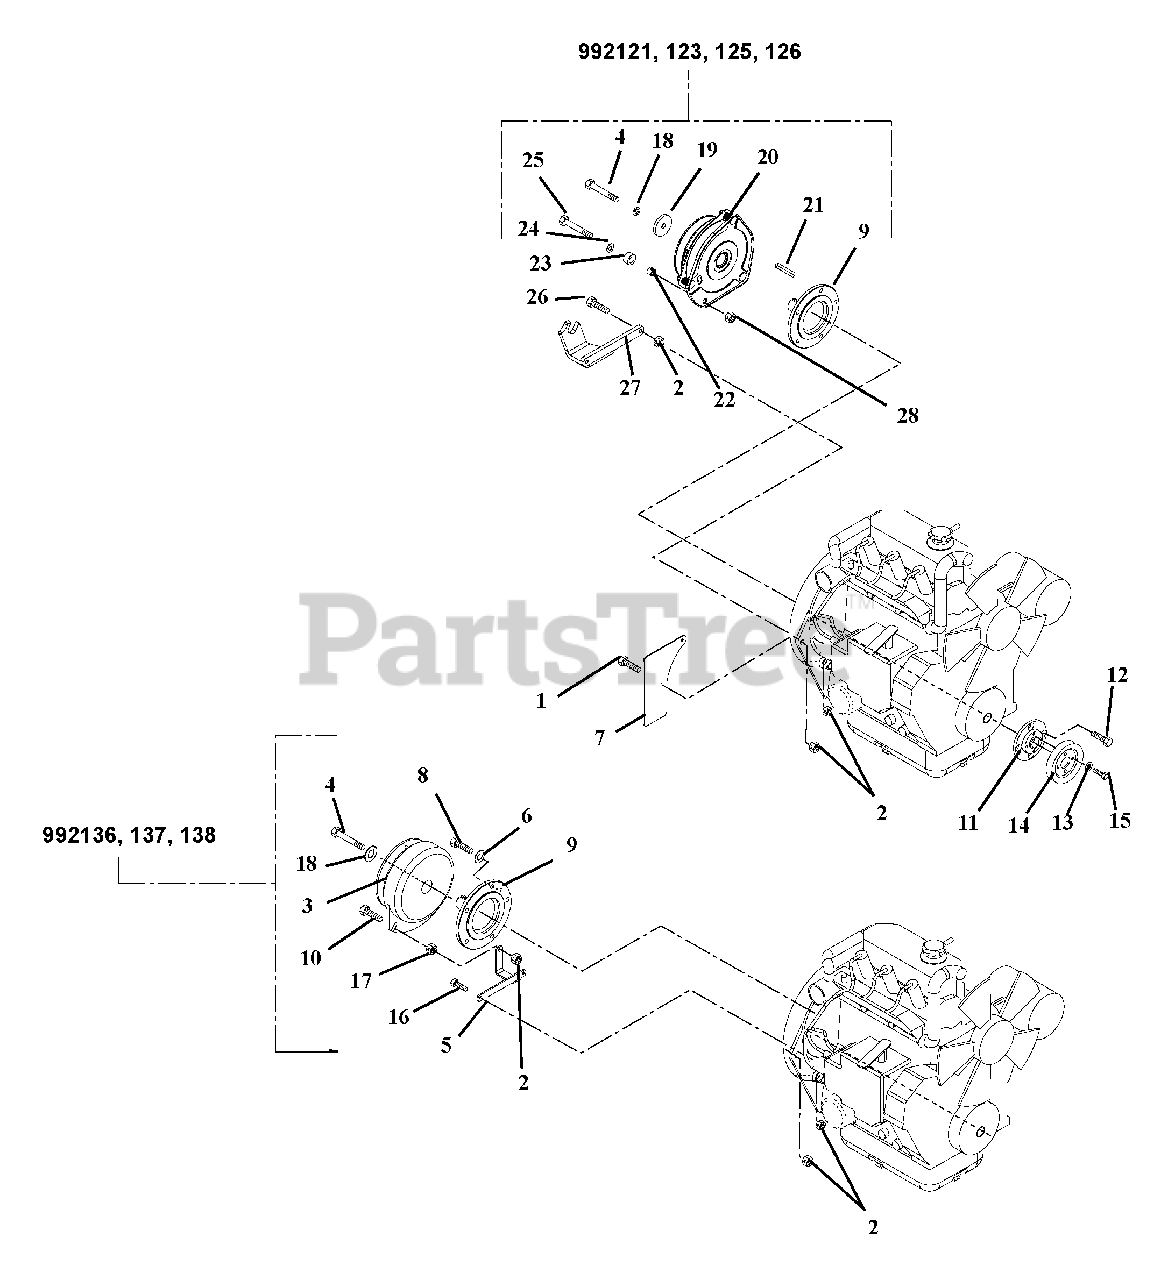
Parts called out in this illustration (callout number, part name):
1	Bolt, Hex .31 -18 x .75 Grade 5
2	Nut, Locking Top Flange .31-18
3	Clutch, Warner
4	Bolt, Hex .44-20 x 2.50 Grade 5
5	Stabilizer, Clutch
6	Washer, Lock .31 x .078 Regular
7	Guard, Flywheel
8	Bolt, Hex M8 x 1.25 x 25 Grade 8
9	Stub Shaft
10	Bolt, Hex .31-18 x 1.50 Grade 5
11	Adapter, Sheave
12	Bolt, M8-1.25 x 25
13	Washer, Locking .25 x .062
14	Sheave, Poly-V 1.0 x 3.25
15	Bolt, Hex .25-20 x .75 Grade 5
16	Bolt, Hex .31-18 x 1.00 Grade 5
17	Nut, Hex .31-18
18	Washer, Locking .44 x .109 Regular
19	Washer, Flat Steel .469 x 2.00 x .25
20	Clutch, Ogura
21	Key .25 x .25 x 2.25
22	Spacer .375 x .686 x .5/6 Steel
23	Bumper, Rubber .62 x 1.0 x .51
24	Washer, Flat Steel .406 x .812 x .065
25	Bolt, Hex .38-16 x 1.00 Grade 5
26	Bolt, Hex .31-18 x 1.25 Grade 5
27	Bracket, Clutch Stop
28	Nut, Hex Jam .375-16
NS	Kit, Break Pole Module Replacement
